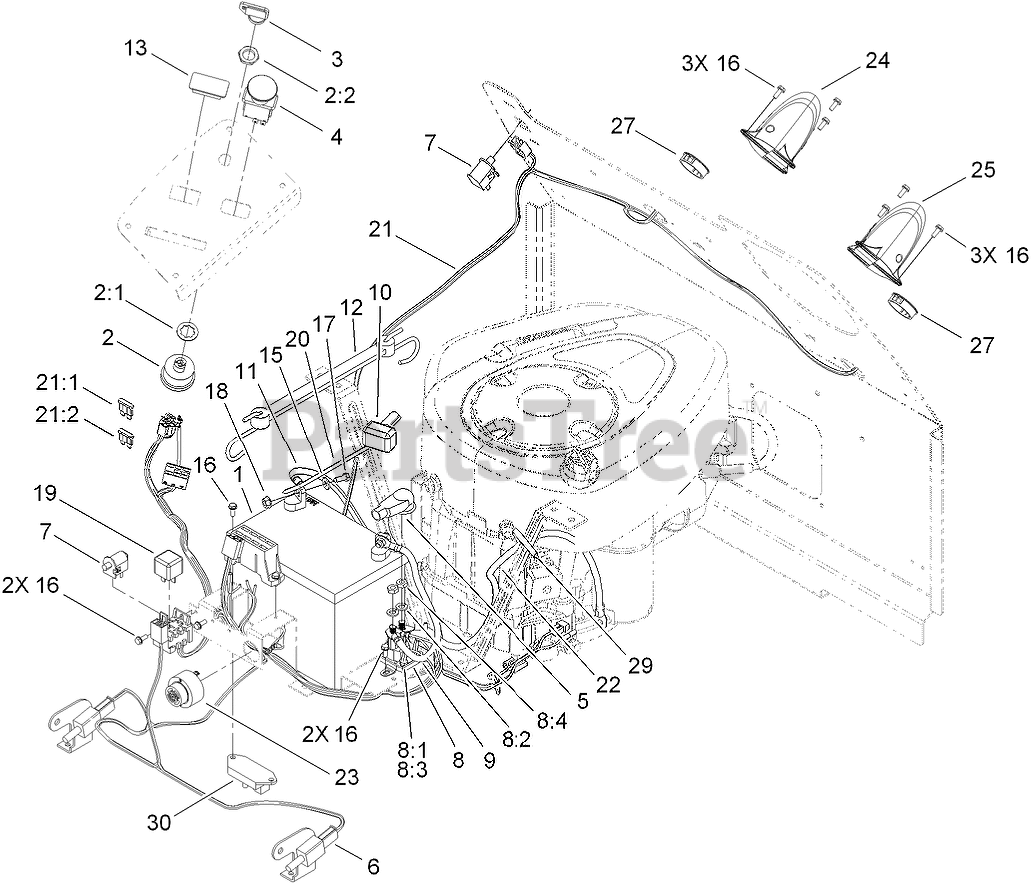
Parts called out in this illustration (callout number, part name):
1	BATTERY
2	Key Switch ASM
2:1	WASHER-TOOTH, INTERNAL
2:2	NUT-HH
3	KEY-IGNITION
4	SWITCH-PTO
5	BOOT-TERMINAL
6	SWITCH
7	SWITCH-BAIL
8	SWITCH-SOLENOID
8:1	WASHER-LOCK
8:2	WASHER-LOCK
8:3	NUT-HEX
8:4	NUT-JAM
9	CABLE-BATTERY, POSITIVE
10	BOOT-INSULATOR, TERMINAL
11	CABLE-NEGATIVE, BLACK
12	HOLDDOWN-BATTERY
13	PLUG-HOLE
15	WASHER-FLAT
16	SCREW-TAPTITE
17	SCREW-HH
18	NUT-HF
19	RELAY
20	TIE-CABLE
21	HARNESS-WIRE
21:1	FUSE-BLADE, 30 AMP
21:2	FUSE-BLADE, 25 AMP
22	WIRE-21 INCH
23	ALARM-TONE, DUAL
24	BAG SENSOR ASM
25	BAG SENSOR ASM
27	BUSHING-HARNESS, WIRE
29	CLAMP-HOSE
30	MODULE-DELAY
